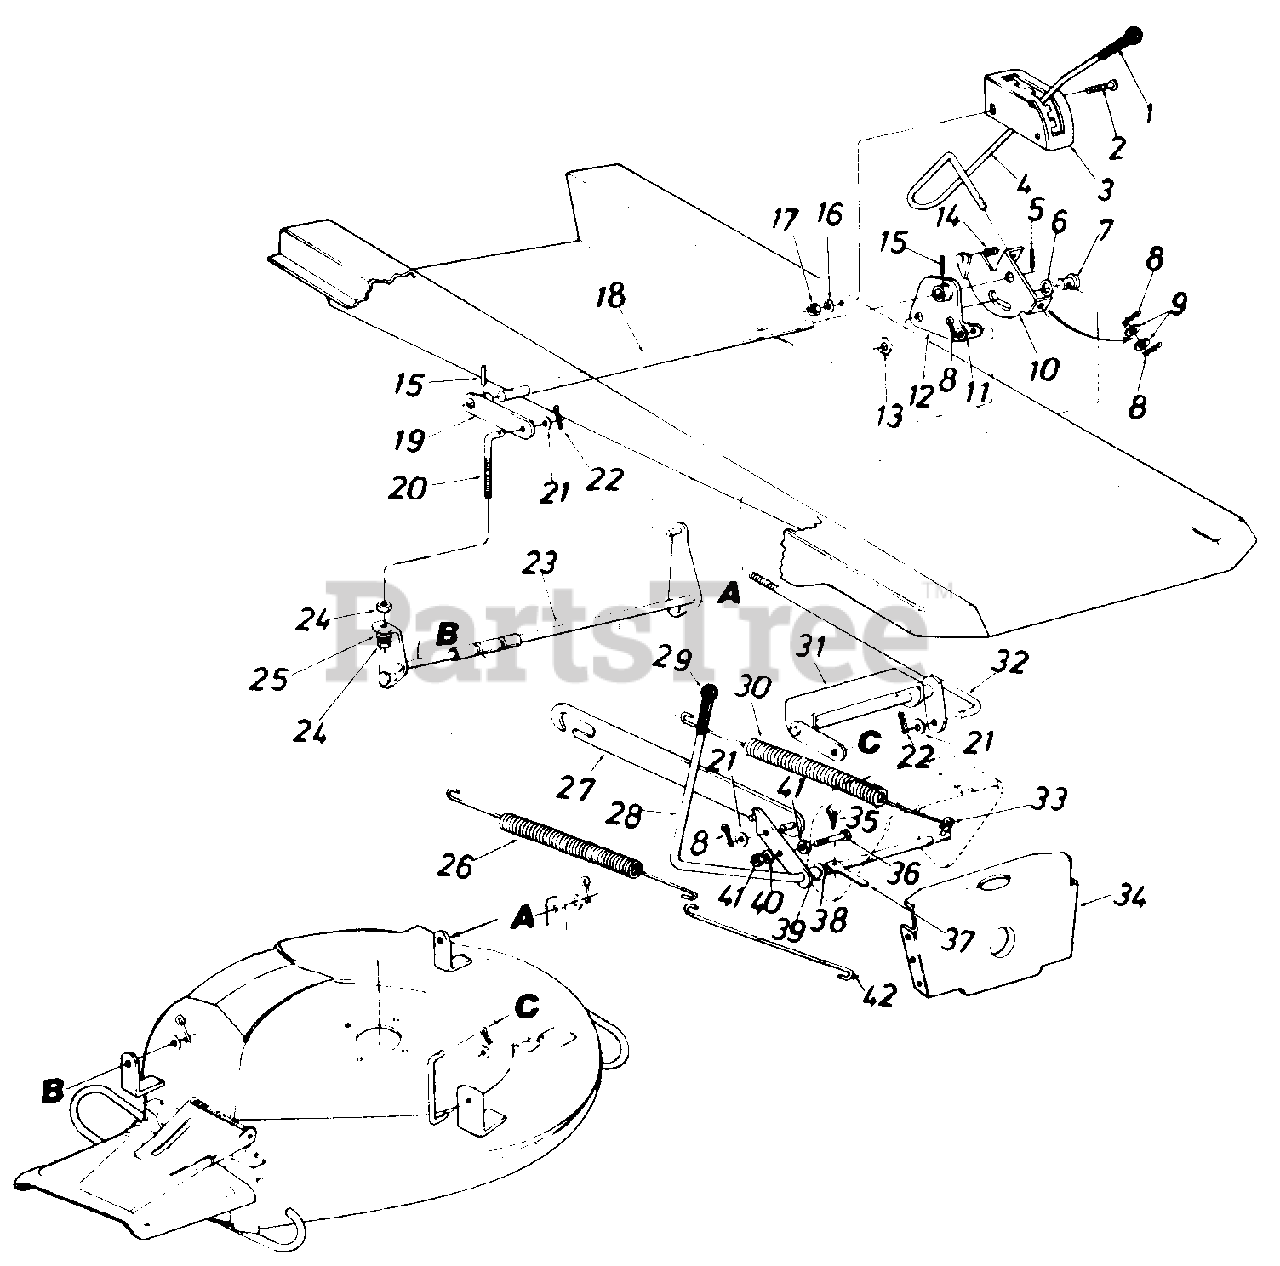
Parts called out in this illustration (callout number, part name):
2	Truss Mach. Scr. 5/16-18 x .75" Lg.
5	Spring Pin Spir. 3/16" Dia. x 1.50" Lg.
6	Fl-Wash. .385" I.D. x .87"
7	Adj. Ferrule Deck Lift Handle
8	Cotter Pin 1/8" Dia. x 1.0"
9	Fl-Wash. .531" I.D. x .930"
10	Deck Lift Handle Retainer Ass'y.
11	Fl-Wash. .385" I.D. x .87"
12	Deck Lift Brkt. Ass'y. L.H.
13	Fl-Wash. .635" I.D. x 1.04"
14	Compression Spring .50" Dia. x 1.0" Lg.
15	Spring Pin Spir. 1/4" Dia. x 1.50" Lg.
16	L-Wash. 5/16" I.D.
17	Hex Nut 5/16-18 Thd.
18	Rear Hgt. Adj. Shaft
19	Deck Lift Brkt. Ass'y. R.H.
20	Deck Adj. Scr. 3/8-16 Thd.
21	Fl-Wash. .385" I.D. x .87"
22	Intern. Cotter Pin 1/2" Dia.
23	Deck Link Ass'y. Rear
24	Hex Nut 3/8-16 Thd.
25	L-Wash. 3/8" I.D.
26	Extension Spring .73" O.D. x 1 3.84" Lg.
27	Deck Drive Control Bracket
28	Blade Engagement Lever Ass'y.
30	Extension Spring .73" O.D. x 13.89" Lg.
31	Deck Lift Ass'y. Front
32	Deck Lift Connecting Rod
33	Clevis Pin Special .250" Dia.
34	Pivot Bar eracket
35	Hex TT-Tap Scr. 1/4-20 x .75"
36	Hex Bolt 5/16-18 x 1.50" Lg. (Grade 5)
37	Switch Actuator
38	Fl-Wash. .531" I.D. x .930
39	Spacer .511" I.D. x .70" O.D. x.38" Lg.
40	L-Wash. 5/16" I.D.
41	Hex Nut 5/16-18 Thd.
42	Spring Hook
